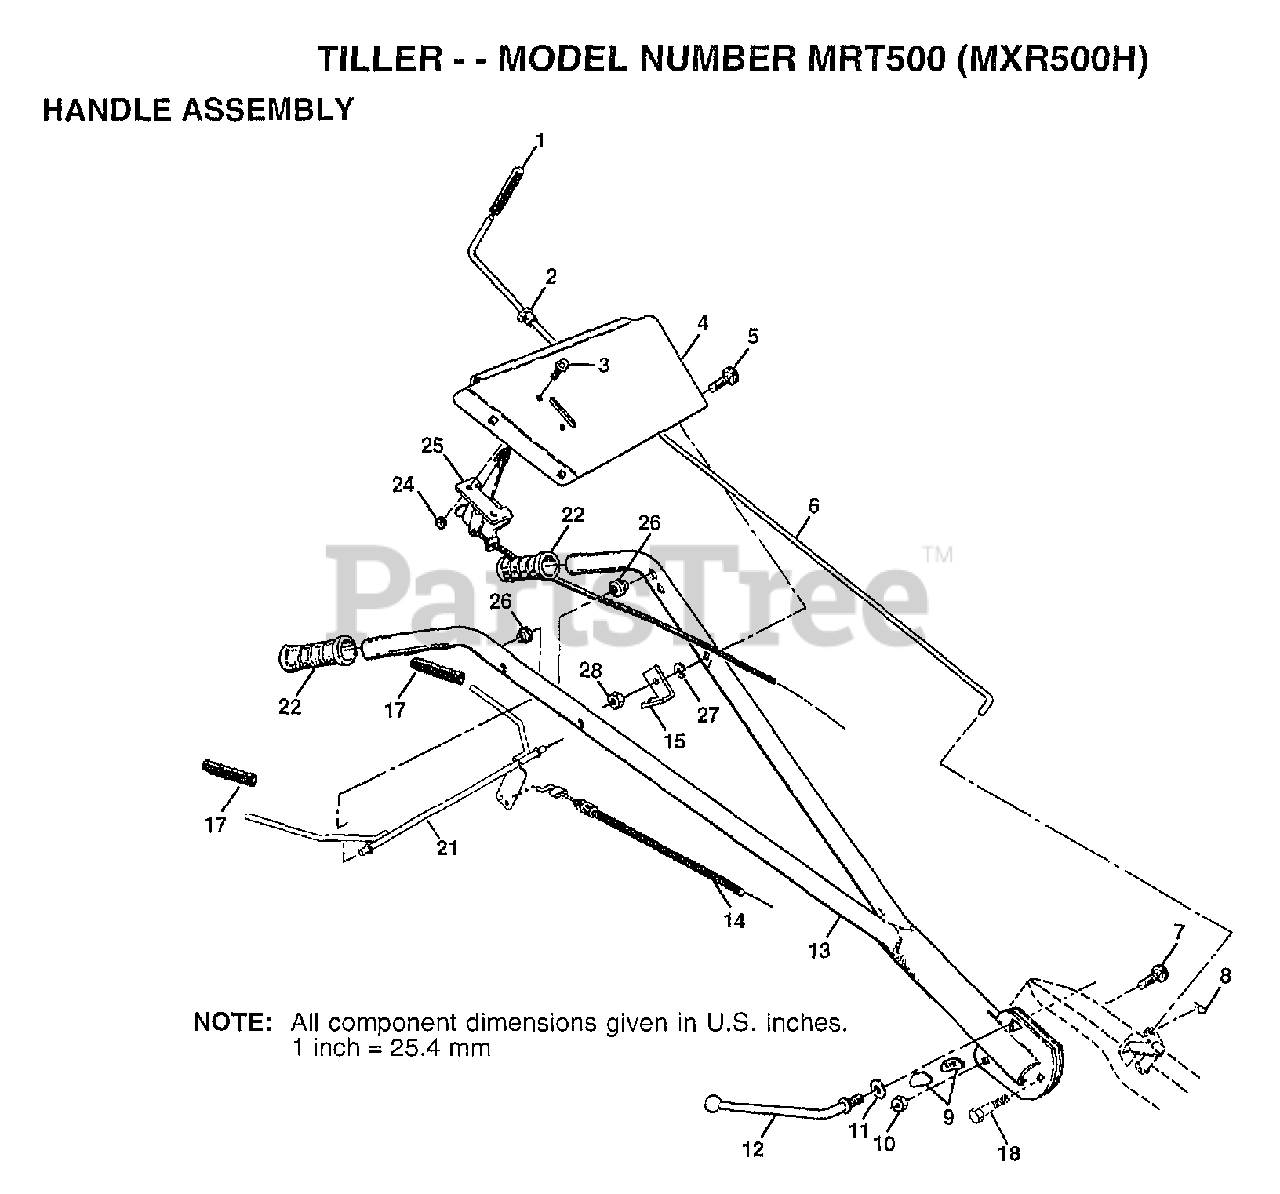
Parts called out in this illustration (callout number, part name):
1	GRIP TI
2	BUSHING
3	SCREW.PNHD.10-24
4	HANDLE BRACKET
5	BOLT CARRIAGE CRT
6	ROD SHIFT CRT
7	BOLT D
8	RETAINER M
9	LOCK CRT
10	LOCKNUT
11	WASHER CRT
12	LEVER LOCK CRT
14	"CABLE, CLUTCH"
15	BRACKET.CLUTCH.CA
17	GRIP BAR CRT
18	BOLT PIVOT
21	BAR CONTROL
22	"GRIP,HANDLE"
23	NUT
25	"CONT,THROTTLE"
26	GROMMET.HANDLE.V-
27	LOCKWASHER
